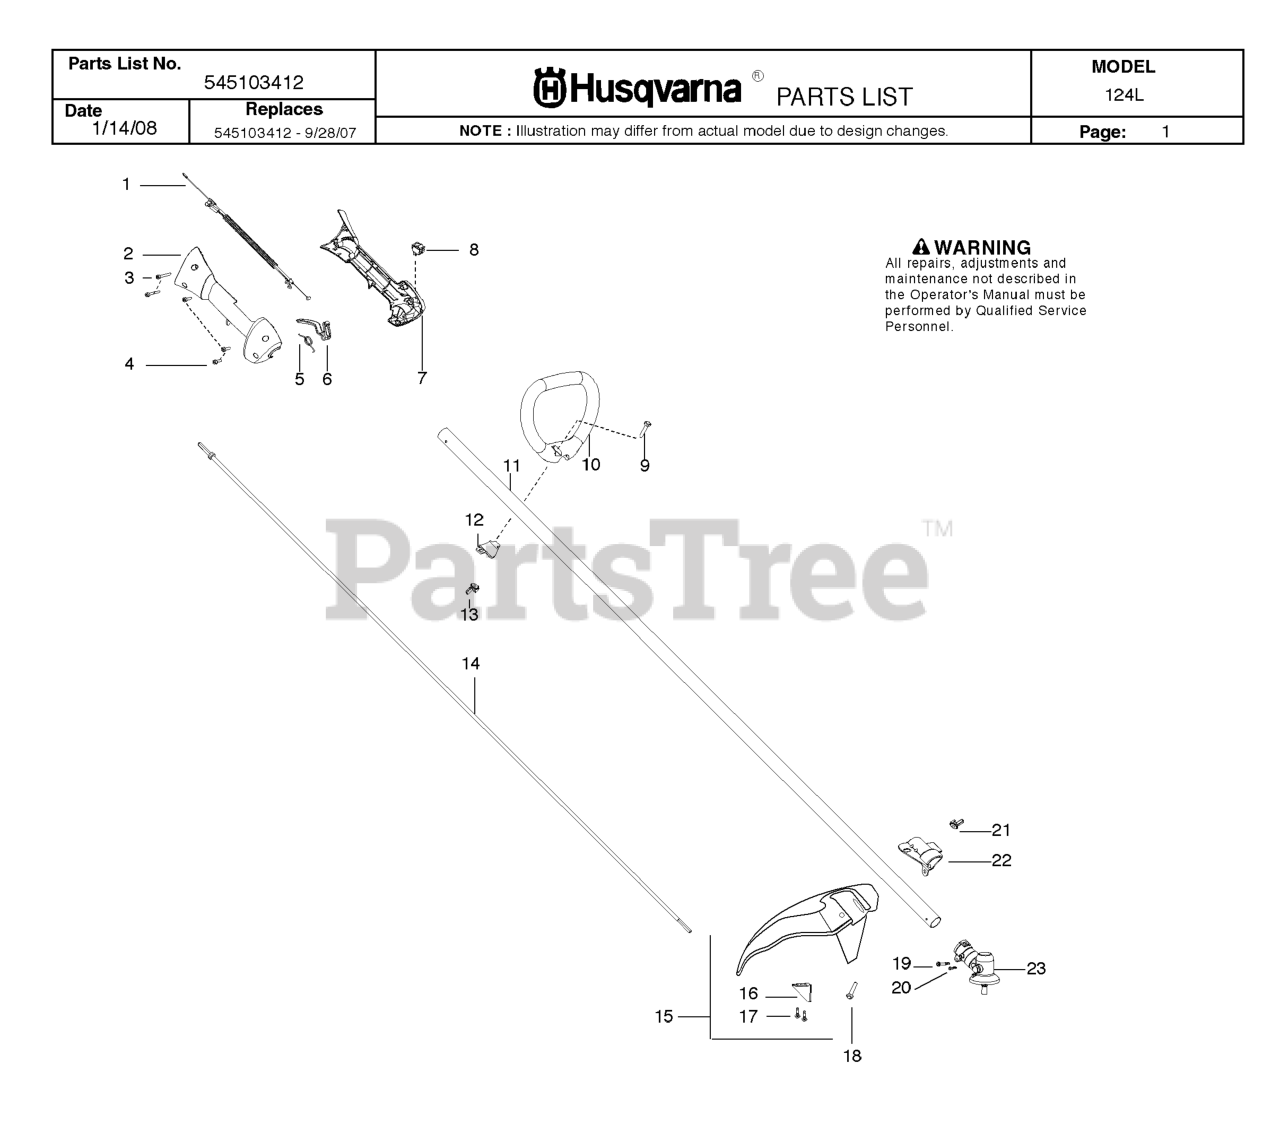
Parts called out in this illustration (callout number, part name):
2	HOUSING-THROTTLE (RH)
4	SCREW M4 X 1.75 PT 16MM
5	SPRING TRIGGER
6	TRIGGER THROTTLE
7	HSG THROTTLE LH
8	KIT SWITCH
9	BOLT, TYPE 2
10	HANDLE ASSIST
11	KIT DRIVESHAFT SST
12	CLAMP ASSIST HANDLE
13	WINGNUT, TYPE 2
15	KIT-SHIELD
16	LINE LIMITER 17"
18	BOLT, TYPE 2
19	SCREW - CARB. ADAPTOR
20	SCREW 8-16 X 9/16 (PLAS
21	WINGNUT, TYPE 2
